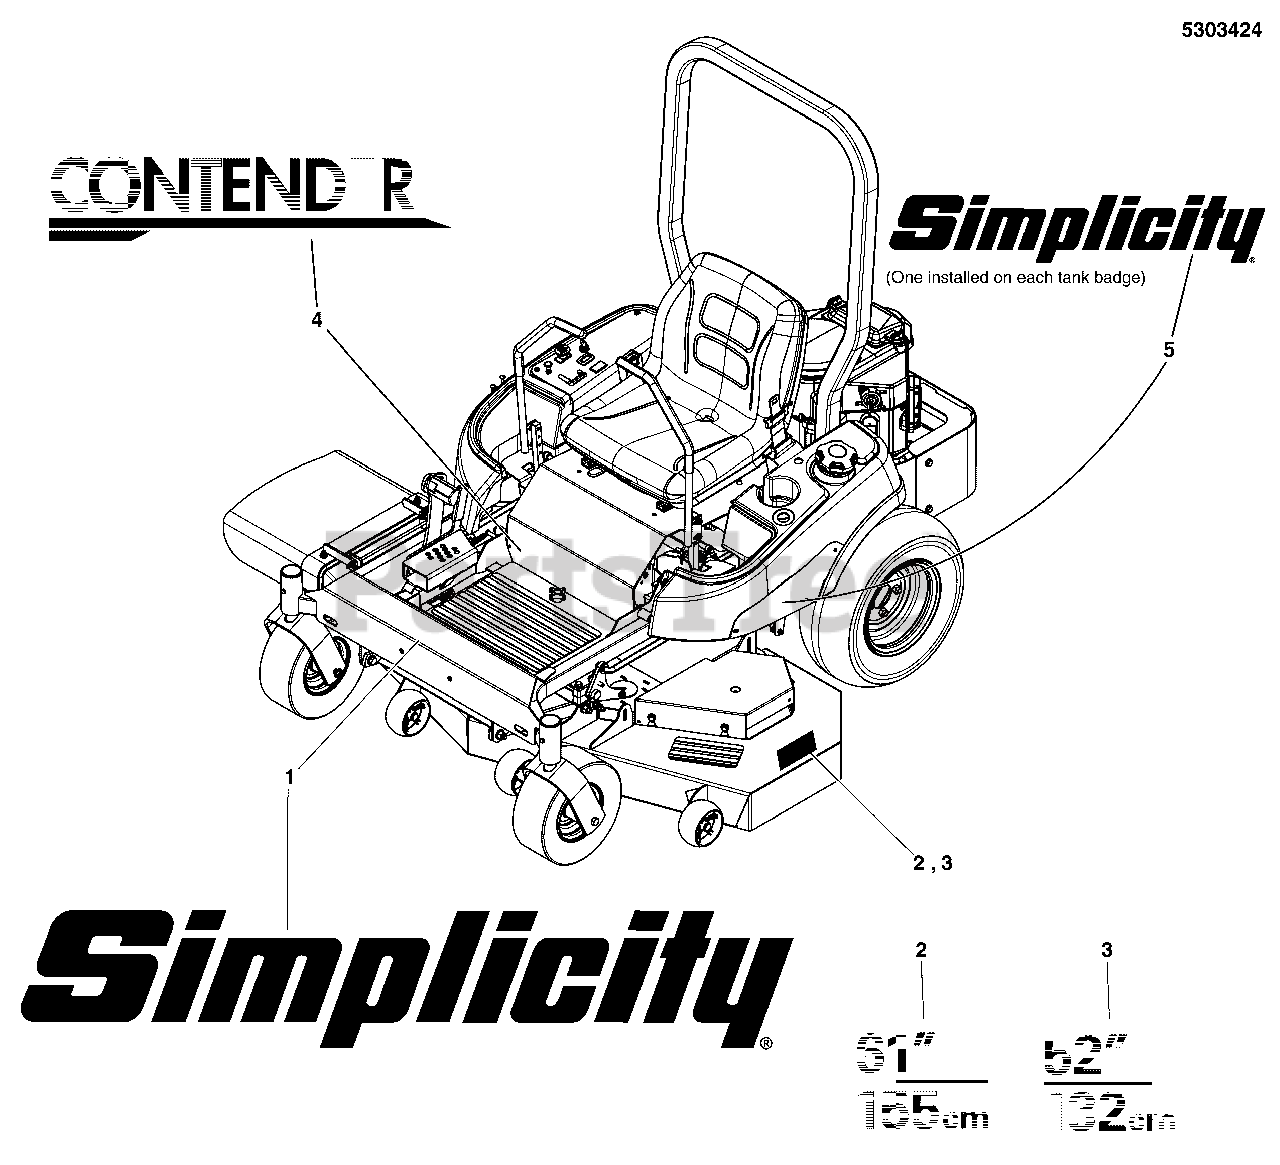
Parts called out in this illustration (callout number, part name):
1	DECAL, SMI LOGO 10.47"
2	DECAL, MOWER WIDTH 52IN/132CM
3	DECAL, MOWER WIDTH 61IN/155CM
4	DECAL, MODEL, CONTENDER
5	DECAL, LOGO SIMPLICITY SILVER
